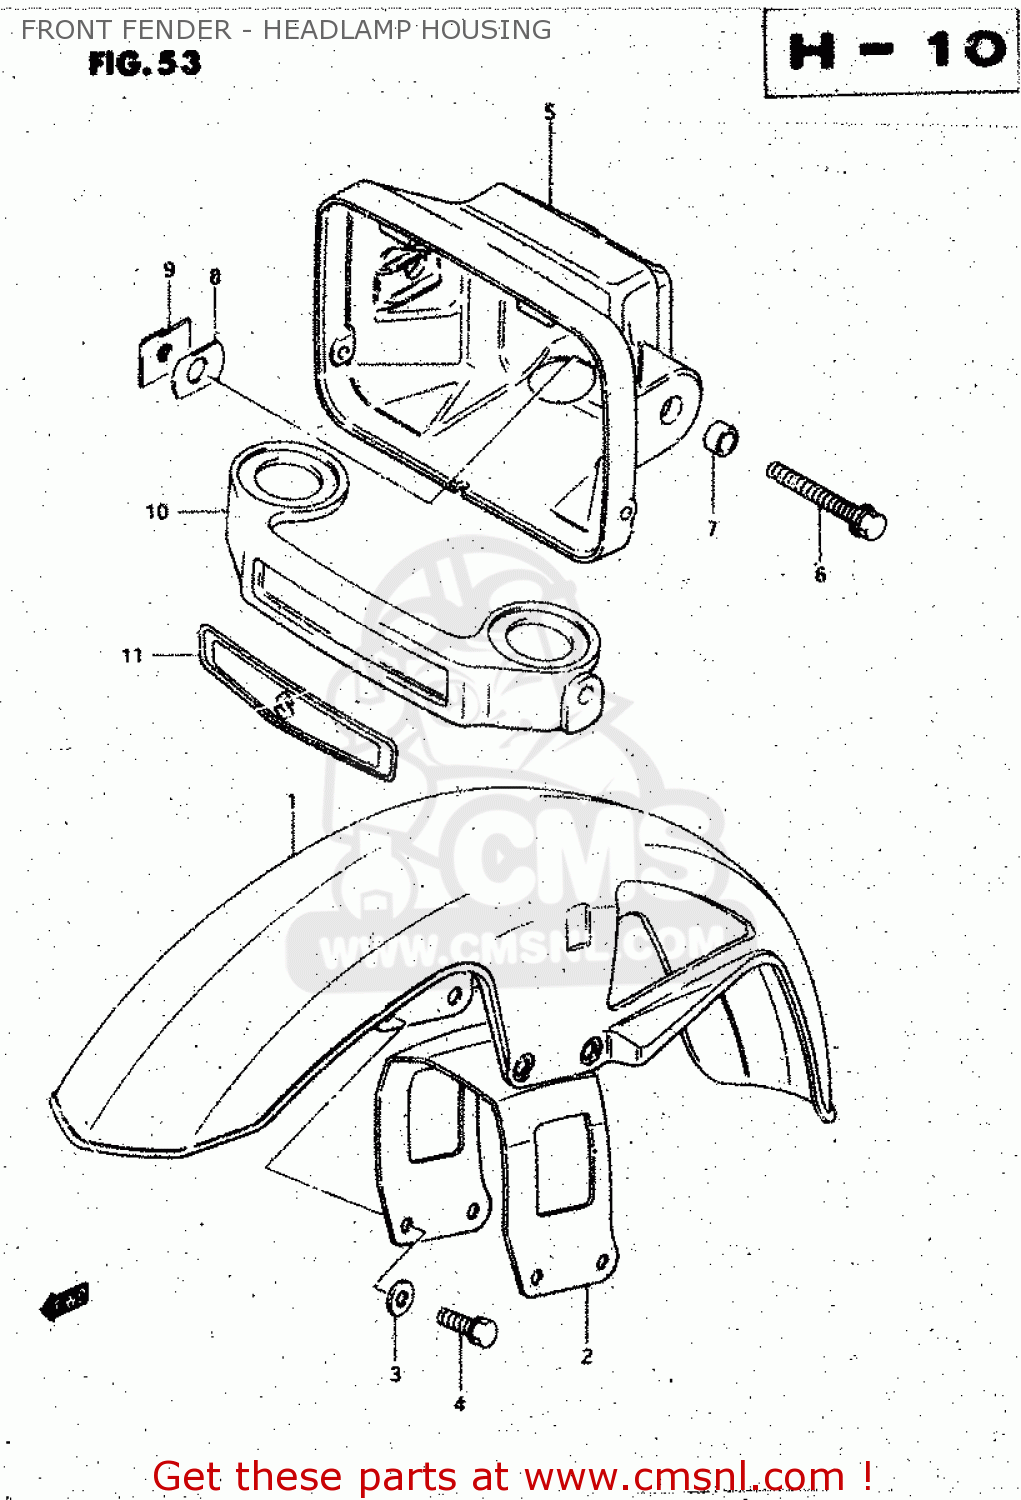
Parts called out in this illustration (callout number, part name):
1	FENDER,FR
2	BRACE,FR FENDER
3	WASHER
4	BOLT, UPPER
5	HOUSING,HEADLAMP
6	BOLT
7	SPACER (8.8X12X7)
8	CUSHION
9	PLATE,HEADLAMP HOUSING
10	COVER,FR FORK
11	EMBLEM,FR FORK COVER
